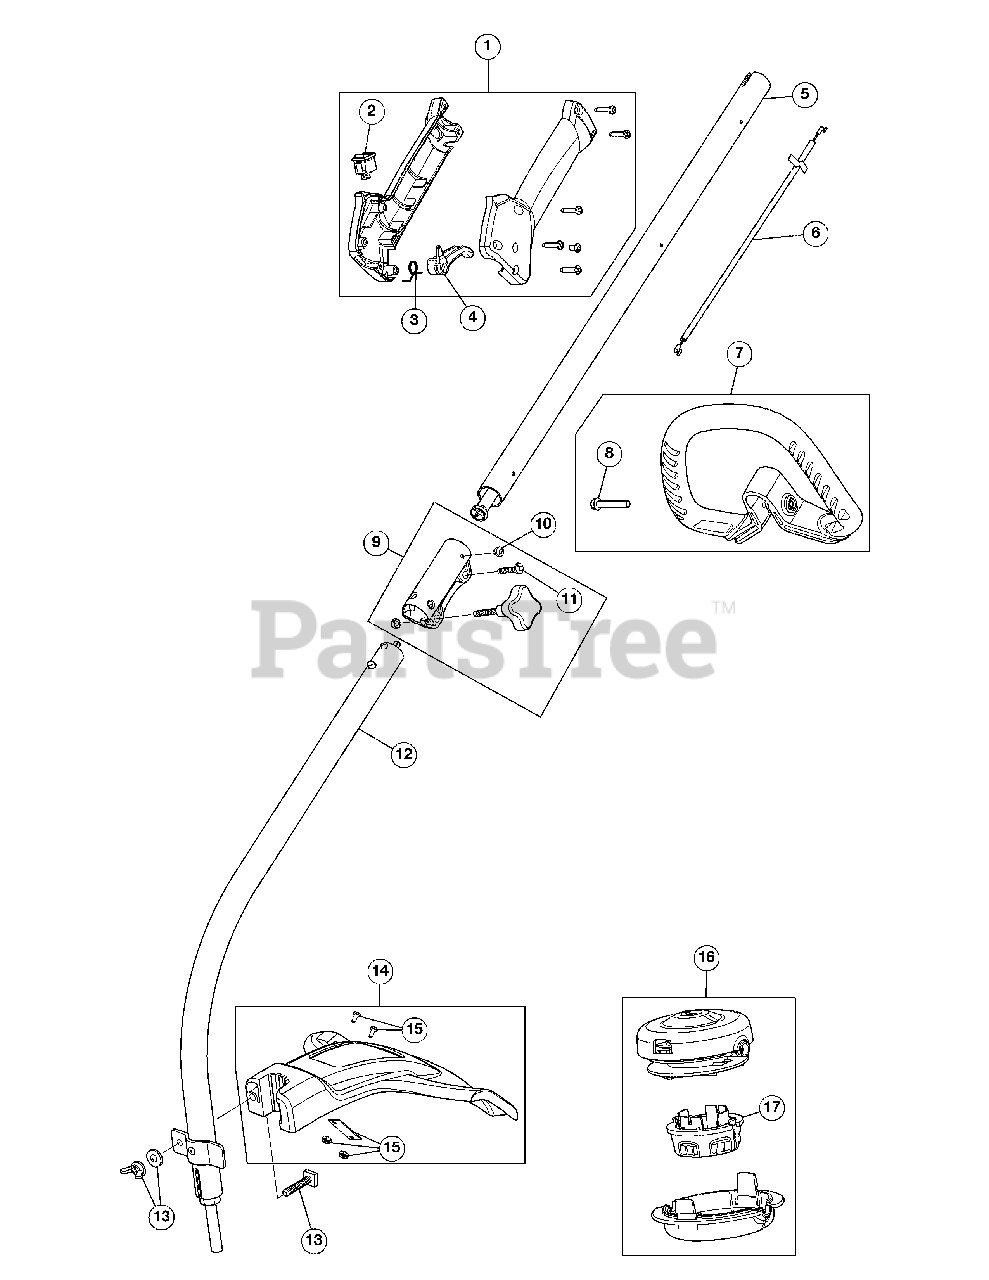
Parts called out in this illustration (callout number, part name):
1	Throttle Housing Assembly (Incl. 2-4)
2	Switch Assembly
3	Throttle Trigger Spring
4	Throttle Trigger
5	Upper Drive Shaft Assembly
6	Throttle Cable Assembly
7	D-Handle Assembly (Incl. 8)
9	Split Boom Coupler (Incl. 10-11)
10	Coupler Anti-Rotation Screw
11	Coupler Bolt
12	Lower Drive Shaft Housing
13	Shield Mount Hardware
14	Shield Assembly (Incl. 15)
15	Blade Assembly
16	Cutting Head Assembly (Incl. 17)
